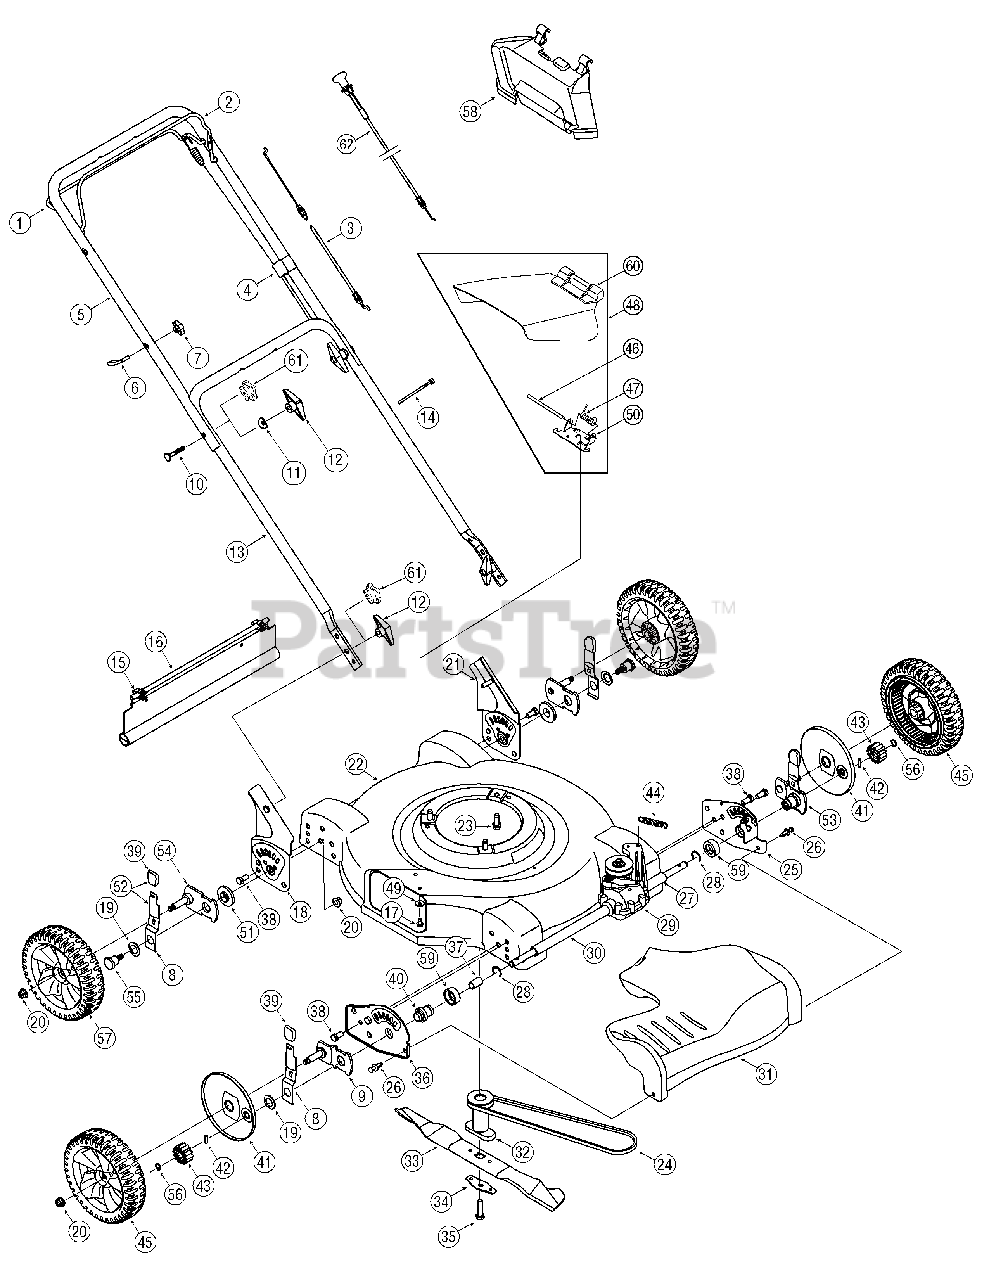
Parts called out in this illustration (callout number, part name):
1	Drive Control Handle
3	Blade Control Cable 50.56" Lg.
4	Drive Control Cable
6	Rope Guide Bolt
7	Knob - ERS Guide 1/4-20
8	Spring Lever
9	Pivot Arm Assembly
10	Carriage Bolt 5/16-18 x2.0
11	Saddle Washer .32 ID x .93 OD x .06
12	Wing Nut
14	Cable Tie
15	Hinge Clip
16	Trail Shield
17	Hex Wash S-Tapp Screw 1/4-20 x .50
20	Flanged Lock Nut 3/8-16
23	Hex Wash HD Tap Screw 3/8-16 x .88
24	V-Belt
26	Plastic Rivet
27	Sleeve Spacer .550 ID x 2.22 OD
28	Retainer Ring
29	Transmission Assembly Complete
30	Sleeve Spacer .550 ID x 8.51 OD
31	Transmission Cover
32	Blade Adapter
33	Mulching Blade 22"
34	Bell Blade Support
35	Hex Bolt 3/8-24 x 1.5" LG (Grade 8)
37	Sleeve Brg. .502 x .627 x 1.0
38	Hex Cap Screw 3/8-16 x .75
39	Knob
40	Bearing Support
41	Dust Wheel Cover
42	Pin
43	Spur Gear 14T RH
43	Spur Gear 14T LH
44	Ext. Spring .47 OD 50 x 2.50
45	Wheel Assembly Comp. 8 x 1.8 Spoke bar
46	Hinge Pin
47	Torsion Spring
48	Side Discharge Assembly
49	Cupped Washer .25 ID x .88 OD x .062
50	Chute Adapter
51	Height Adjuster Bearing
52	Lever Assembly
53	Spring Lever Assembly
54	Pivot Arm Assembly
55	Shoulder Screw 3/8-16
56	Screw 1/4-20 X .39
57	Wheel Assembly Comp. 8 x 1.8
58	Snap Mulching Plug
59	Bearing Spacer
60	Chute Deflector
61	Knob - Star 5/16-18
62	Control Cable
